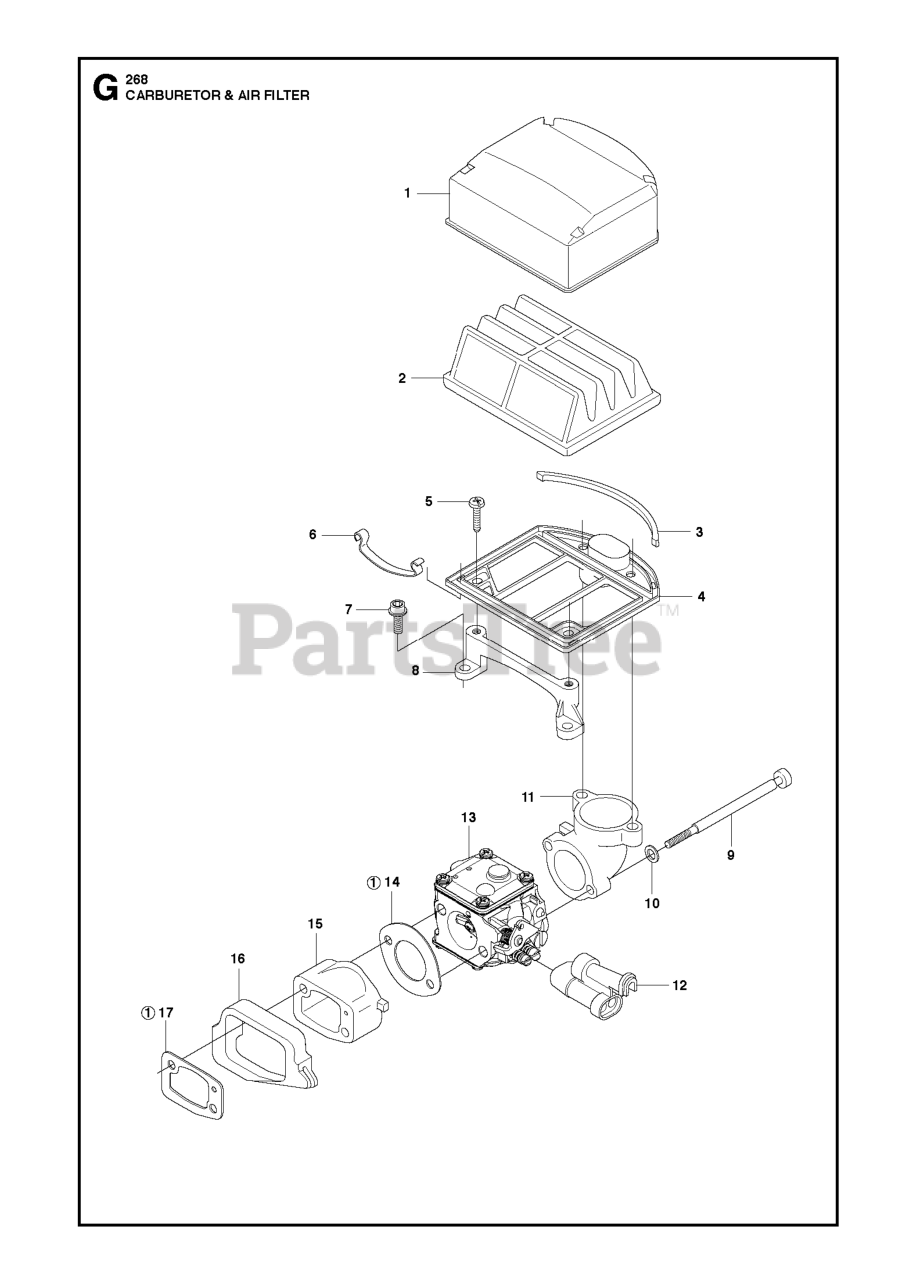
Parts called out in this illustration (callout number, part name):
2	AIR FILTER
2	AIR FILTER - NYLON
4	FILTER HOLDER UPPER
10	WASHER
11	FILTER HOLDER
13	CARBURETOR
16	SEALING COLLAR
